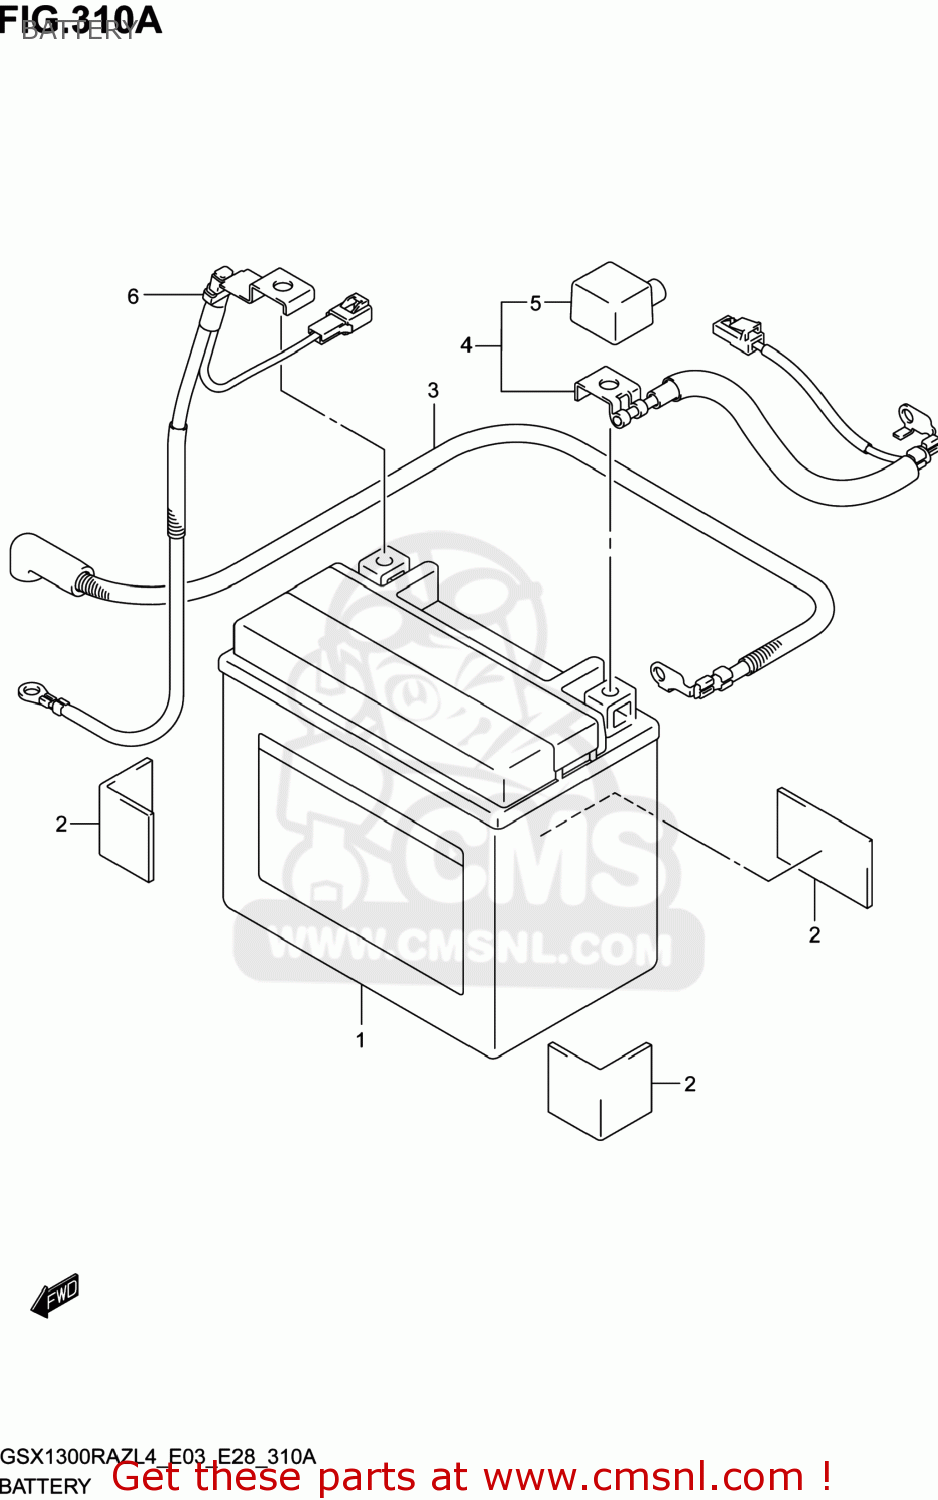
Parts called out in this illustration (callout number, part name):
1	BATTERY ASSY(YTX12-BS,12V10AH)
2	CUSHION(30X50X3)
3	WIRE,STARTER MOTOR LEAD
4	WIRE,BATTERY PLUS LEAD
5	CAP,BATTERY PLUS
6	WIRE,BATTERY MINUS LEAD
